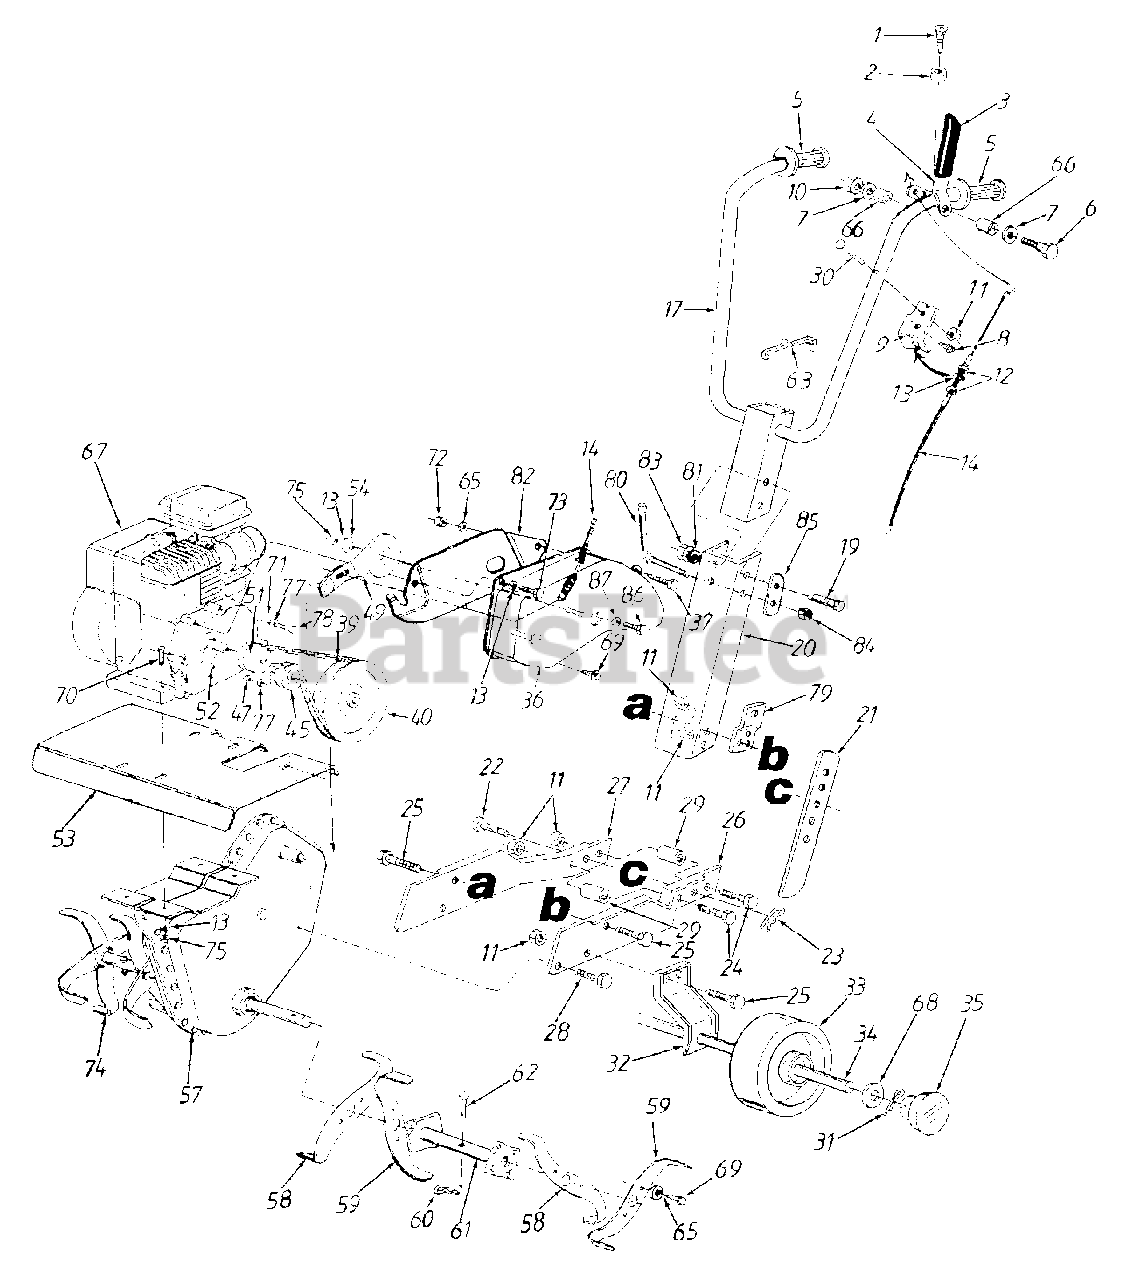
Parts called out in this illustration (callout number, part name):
1	Tap Scr. #10 x 1/2" Lg.
2	Rubber Bumper
3	Vinyl Grip
5	Handle Grip
6	Hex Bolt 1/4-20 x 2" Lg.
7	Fl-Wash. 1/4" I.D.
8	Hex Tap Scr. 1/4-20 x 1/2" Lg.
9	Cable Bracket
10	Lock Nut 1/4-20 Thd.
11	Lock Nut 5/16-18 Thd.
12	Hex Jam Nut 5/16-24 Thd.
13	L-Wash. 5/16" I.D.
14	Clutch Control Cable
23	Hairpin Cotter
24	Hex Bolt 5/16-18 x 1" Lg.
25	Hex Bolt 5/16-18 x 5/8" Lg.
29	Spacer
30	Hex Bolt 5/16-18 x 1-1/4" Lg.
31	Cotter Pin
34	Axle-Wheel
35	Hub Cap
39	V-Belt
40	Pulley-Chain Case
45	Flat Idler Pulley
47	Hex Jam L-Nut 3/8-24 Thd.
49	Idler Arm Ass'y.
51	Engine Pulley
52	Square Key 3/16" x .75" Lg.
57	Chain Case Ass'y. Comp.
63	Cable Tie-Plastic
65	L-Wash. 1/4" I.D.
66	Spacer
67	Engine
68	Fl-Wash. .406 I.D.
69	Tap Scr. 1/4-20 x 1/2" Lg.
70	Hex Bolt 3/8-16
71	Fl-Wash. 3/8" I.D. x 1" O.D.
72	Hex Nut 1/4-20 Thd.
73	Hex Bolt 5/16-24 x .5" Lg.
77	L-Wash. 3/8" I.D.
78	Hex Bolt 3/8-24 x 1" Lg.
81	Fl-Wash. .385" I.D. x .87" O.D.
84	Hex Flange L-Nut 3/8-24 Thd.
85	Retainer Bracket
86	Hex Bolt 5/16-18 x .75" Lg.
87	Fl-Wash. .330 I.D.
